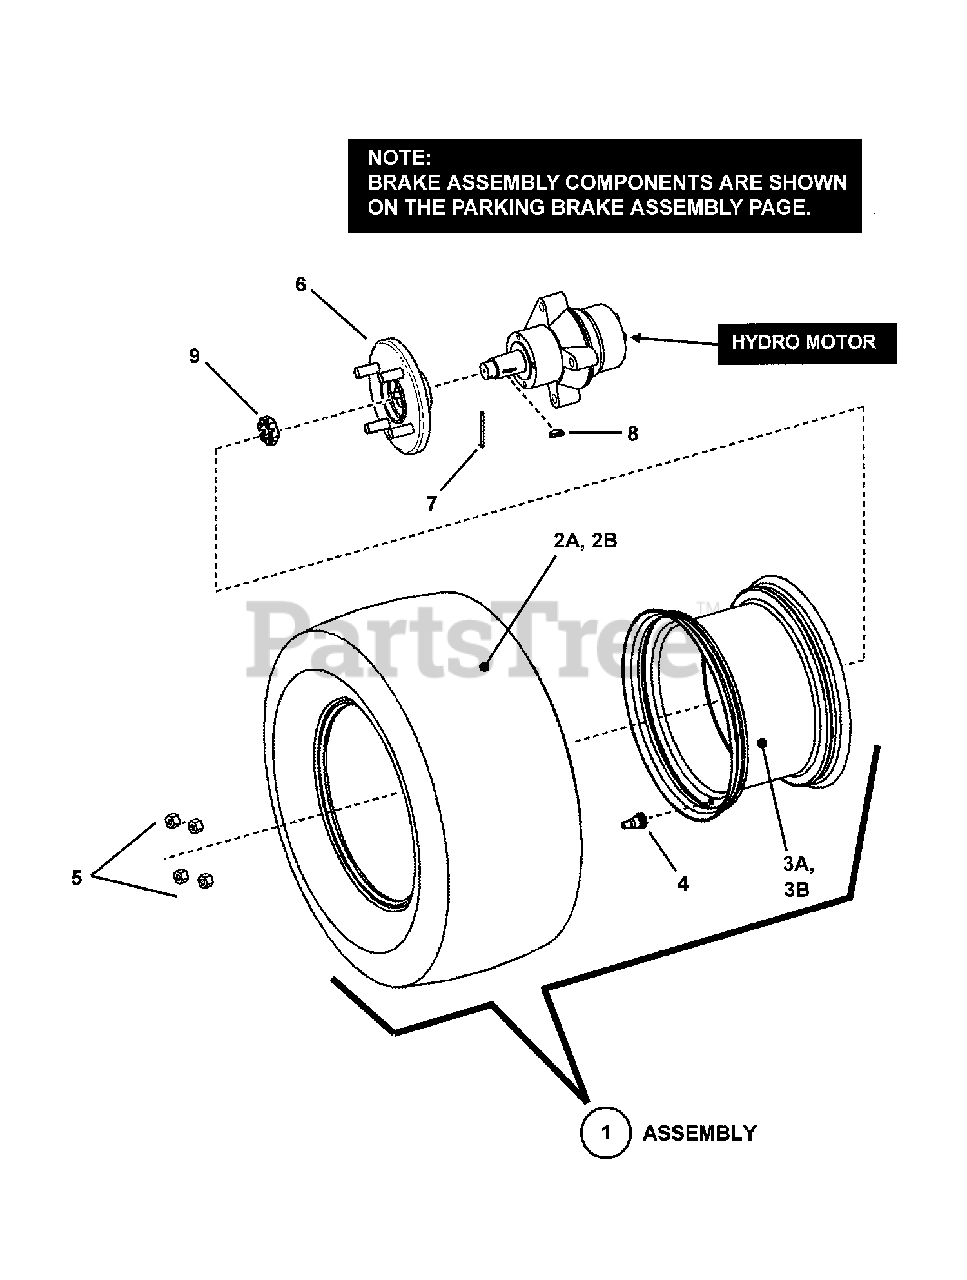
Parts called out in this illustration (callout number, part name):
1	WHEEL ASSY, 20 x 10-10 4 Ply
1	WHEEL ASSY, 22 x 10-10 4 Ply
2A	TIRE, 20 x 10-10 4 Ply
2B	TIRE, 22 x 10-10 4 Ply "Turfmaster"
3A	RIM, 10 x 7.00 4/4
3B	RIM, 10 x 7.00
4	VALVE STEM & CAP
5	LUG NUT, 1/2-20 Tapered Seat
6	BRAKE DRUM
7	PIN, 9/64 x 1-1/2" Cotter
8	KEY, #11 Woodruff
9	NUT, 3/4-20 Slotted Hex
